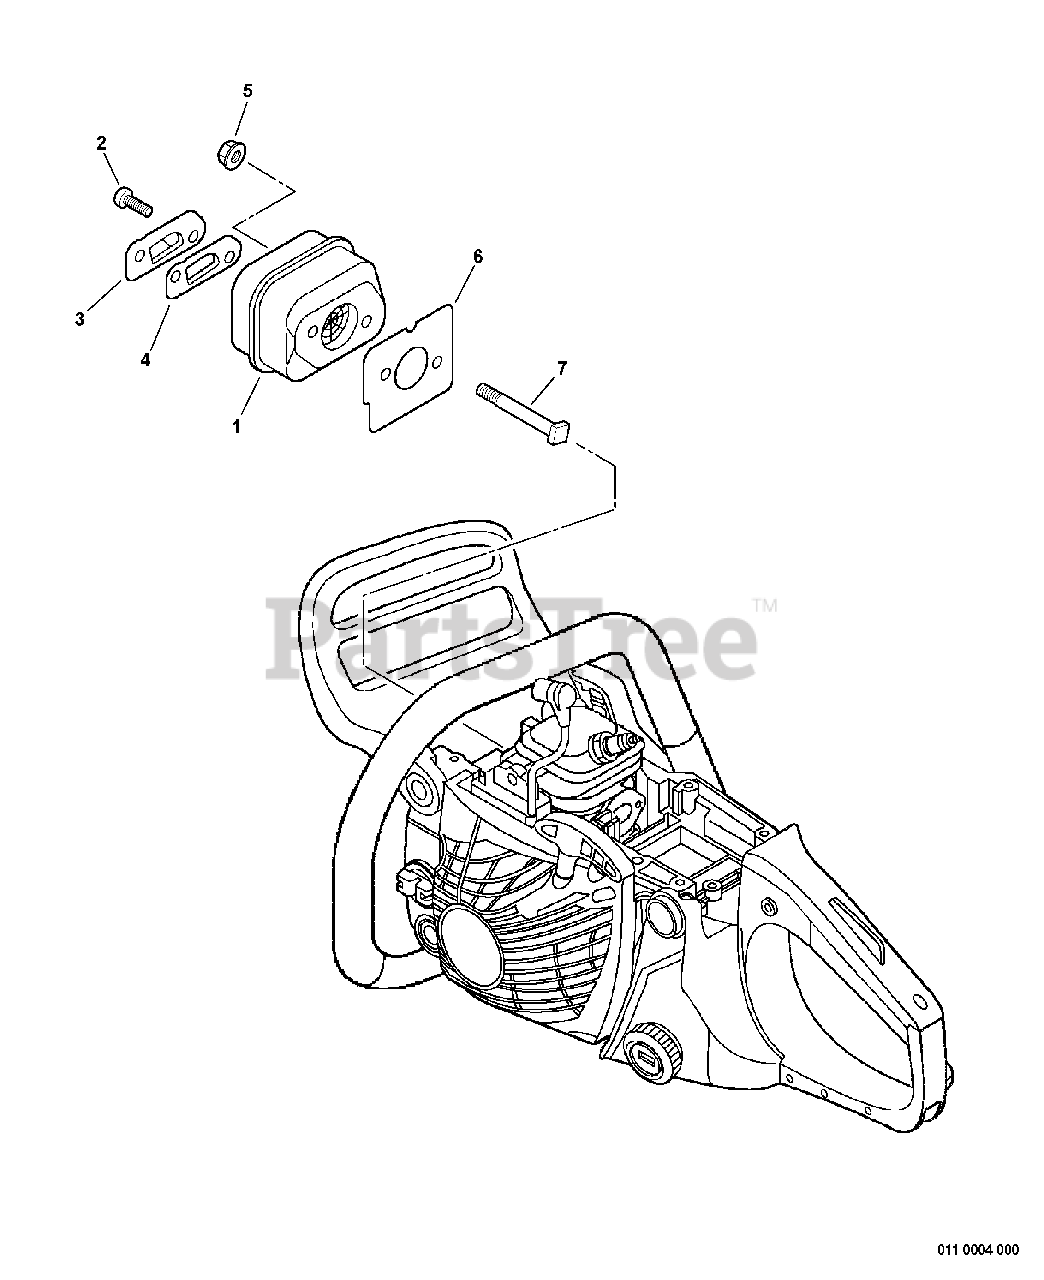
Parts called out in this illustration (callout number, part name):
1	MUFFLER
2	SCREW - 4X8
3	GUIDE, EXHAUST
4	SCREEN, SPARK ARRESTOR
5	NUT - 5 -- FLANGE
6	GASKET, EXHAUST
